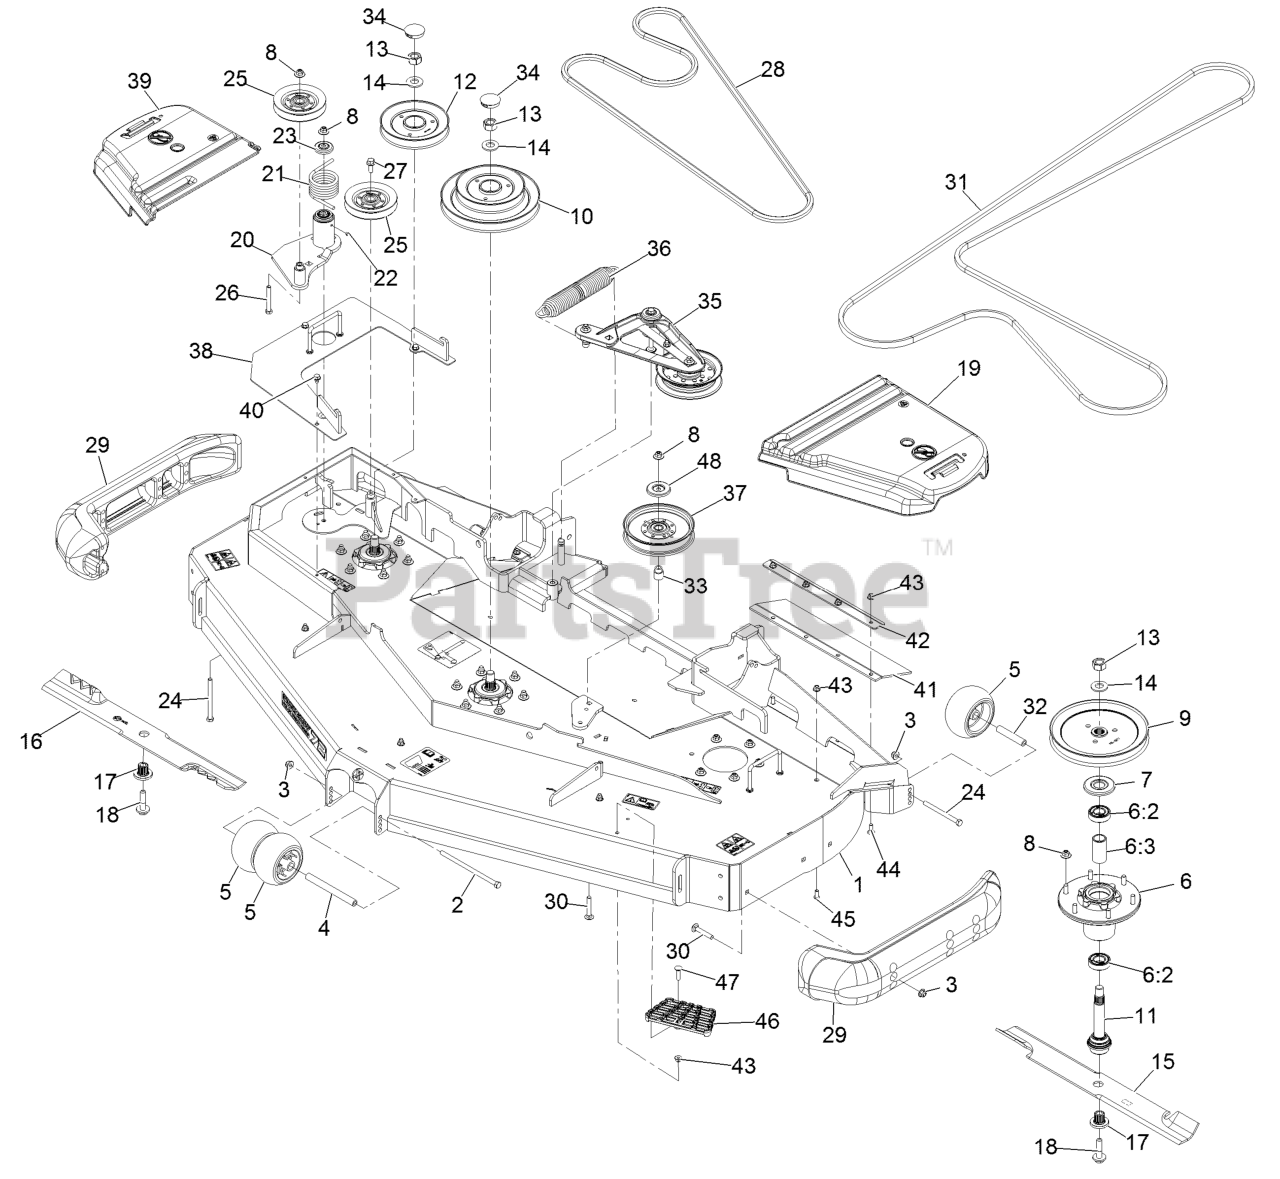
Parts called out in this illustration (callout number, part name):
1	DECK-RD72 NLZ, W/DECALS
2	SCREW-HH
3	NUT-HF, NI
4	SPACER-WHEEL
5	ROLLER-SCALP, ANTI
6	ASM-CUTTER HSG WITH BEARINGS
6:2	BEARING-BALL
6:3	SPACER-BEARING
7	GUARD,BEARING TOP .989
8	Nut-Nyloc 3/8-16 Flg
9	SHEAVE,BLADE DRIVE 8.74
10	SHEAVE, DOUBLE 72RD
11	ASM-SPINDLE AND SEAL
12	SHEAVE-RD REV DRIVE SERIE
13	NUT-HEX
17	BUSHING,SPLINED
18	SCREW,SEMS 1/2-20 X 2.19
19	COVER-BELT, LH
20	IDLER ASM
21	SPRING-TORSION
22	FITTING-GREASE
23	GUARD-TOP
24	SCREW-HH
26	SCREW-HH
27	SCREW-HHF
29	SKID-BUMPER, DECK
30	Bolt-Carriage 3/8-16 X 2 1/4
31	BELT
32	TUBE-SPANNER
33	BUSHING-IDLER
34	PLUG,BLACK NYLON 1.75
35	DECK IDLER ASM
36	SPRING-EXTENSION
37	IDLER-PULLEY, FLAT 6.00X1
38	COVER-REVERSE DRIVE
39	COVER-BELT, RH
41	GUARD-TIRE
42	SUPPORT-OUTER FLAP
43	NUT-HF, NI
44	SCREW-CARR
45	SCREW-HSBH
46	STEP-DECK
47	Bolt-Carriage 5/16-18 X 1 1/4
48	SHIELD-DUST
